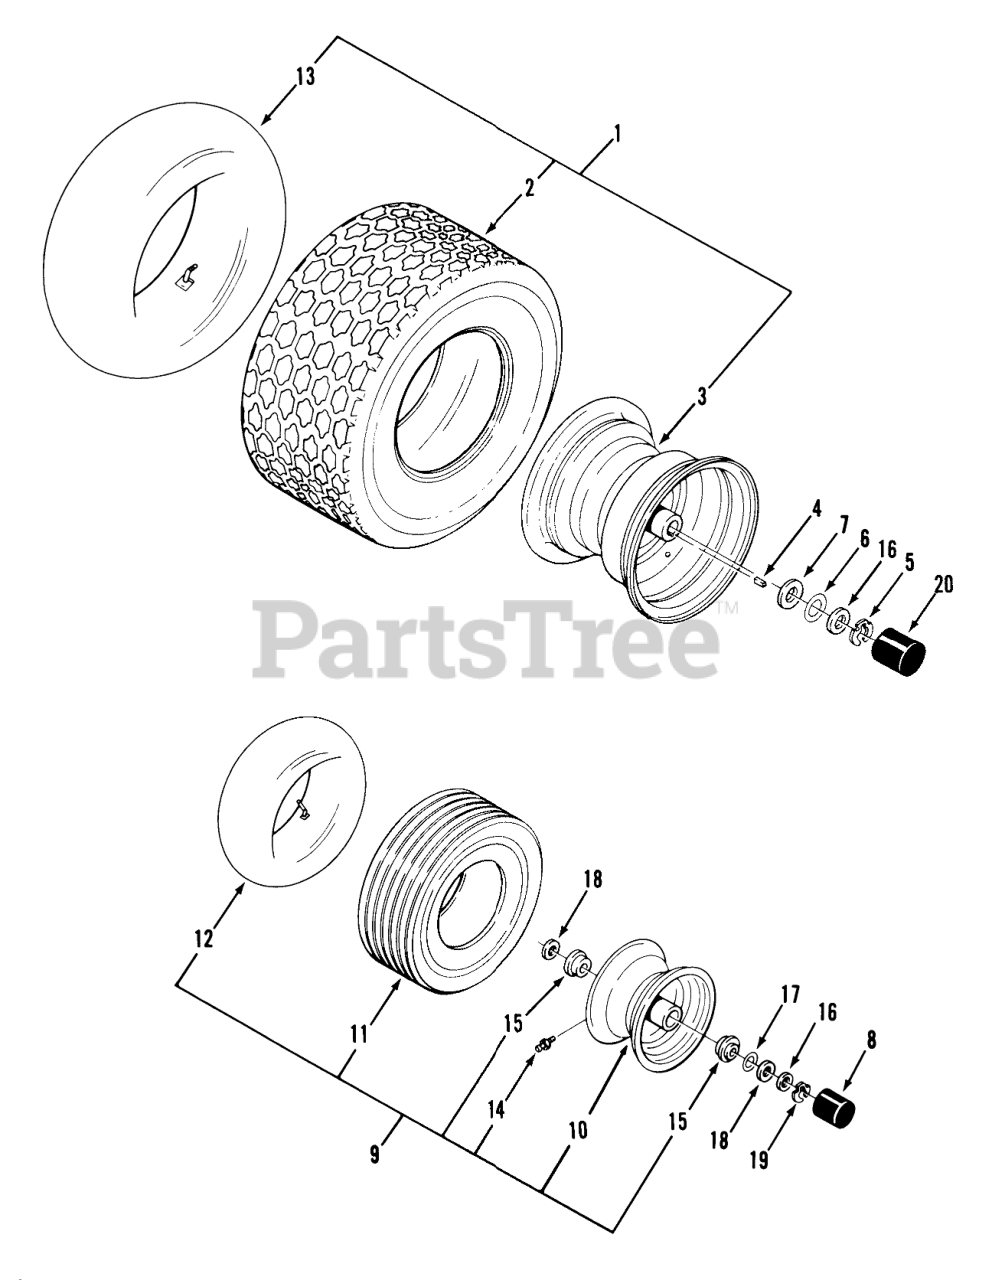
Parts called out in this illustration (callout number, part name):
1	Rear Wheel Assembly 18 x 9.50 x 8
2	TIRE-18X9.50-8 TT RS
3	WHEEL ASS'Y 8"X7
4	Key
5	Retainer
6	Washer
8	HUB CAP-FLAT BLACK
9	Front Wheel Assembly 11 x 4.00-5
10	WHEEL ASS'Y
11	TIRE 11 X 400-5 RIB
12	TUBE-TIRE 11X4.00-5
13	TUBE-TIRE
14	ZERK-GREASE
15	BEARING-WHEEL
16	WASHER-FLAT
17	WASHER-SHIM
18	WASHER-WHEEL
19	KLIP-RING .75"
20	HUBCAP
